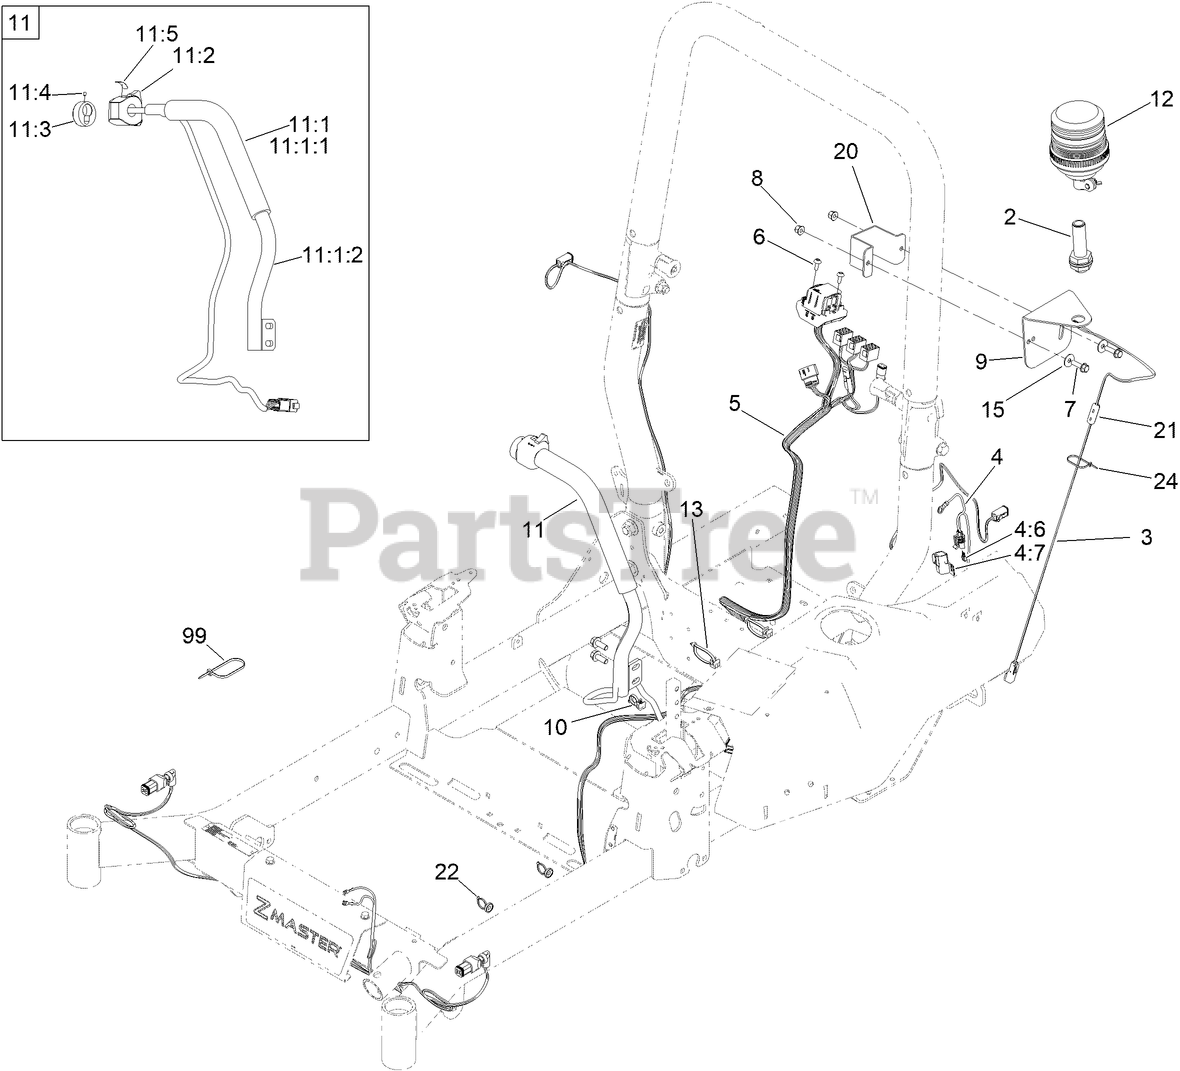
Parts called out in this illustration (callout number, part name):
2	SOCKET-BEACON
3	HARNESS-WIRE
4	HARNESS-WIRE, EU POWER ADAPTOR
4:6	FUSE-MINI BLADE, 20 AMP
4:7	COVER-FUSE, SINGLE
5	HARNESS-WIRE, EU LIGHT KIT
6	SCREW-SOC, HD
7	SCREW-HHF
8	NUT-FLANGE, NI
9	BRACKET,BEACON
10	CLIP-EDGE, W/TIE, SIDE MOUNT
11	LEVER ASM-LH,
11:1	LEVER ASM, LH
11:1:1	GRIP, CONTROL LEVER
11:1:2	LEVER ASM, LH [BLACK]
11:2	SWITCH-COMBINATION ASSEMBLY
11:3	CAP-SWITCH
11:4	SCREW-SET
11:5	DECAL-LIGHTS
12	LIGHT-BEACON ASM
13	CLIP-HARNESS. EDGE, W/TIE-WRAP
15	WASHER-PLAIN
20	CLAMP-60MM
21	FERRITE, EMC SUPPRESION
22	MOUNT-TIE WRAP, MAGNETIC
24	TIE-CABLE
99	TIE-CABLE
